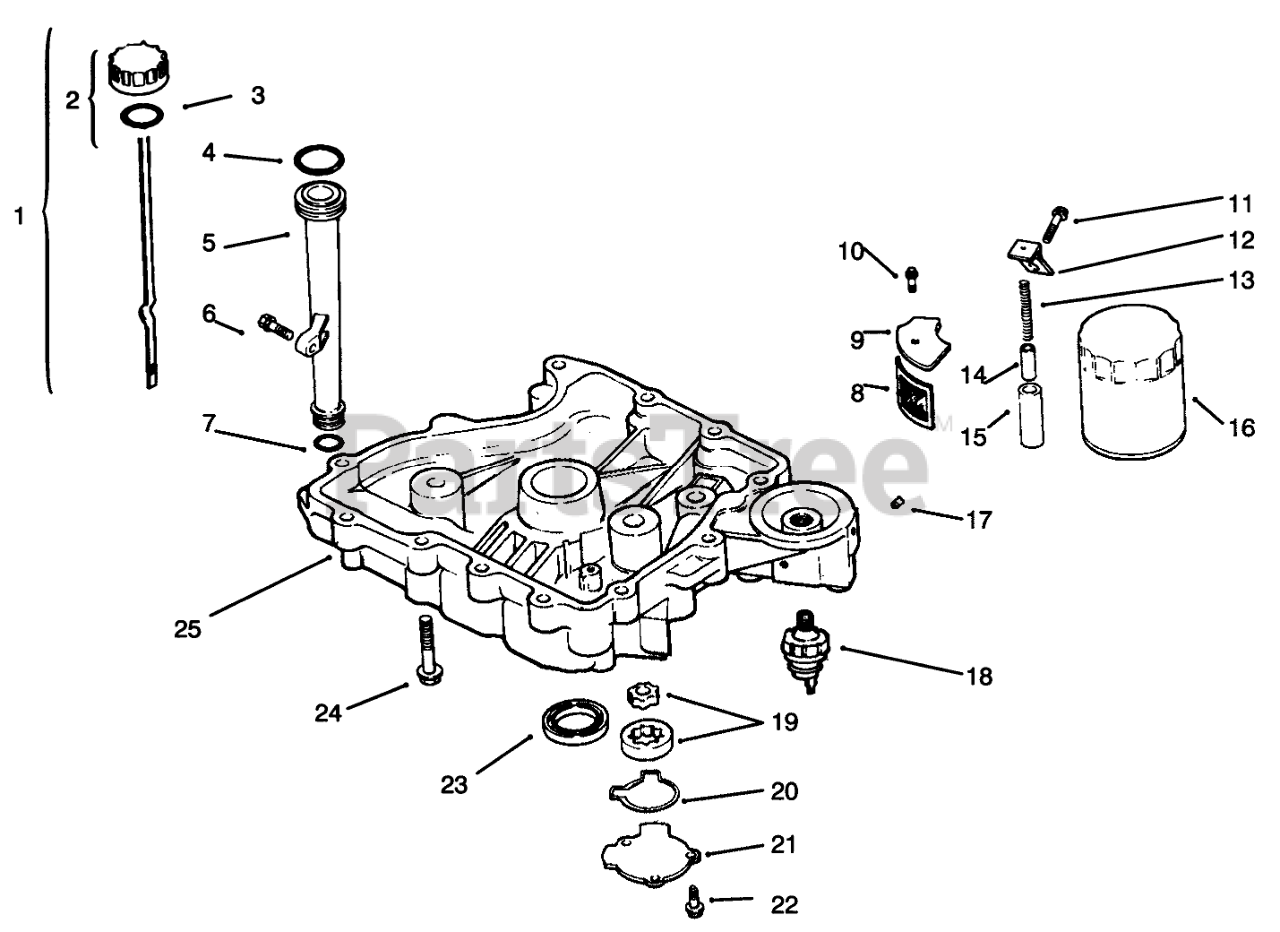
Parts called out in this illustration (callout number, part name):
1	Dipstick INCL 2-3 (Only On: 72042, 72043, 72062, 72063)
2	Kit-Oil Cap INCL 3 (Only On: 72042, 72043, 72062, 72063)
3	O Ring-Fill Cap (Only On: 72042, 72043, 72062, 72063)
4	O Ring-Upper Fill Tube (Only On: 72042, 72043, 72062, 72063)
5	Tube-Oil Fill (Only On: 72042, 72043, 72062, 72063)
6	Screw M5x0.8x20 (Only On: 72042, 72043, 72062, 72063)
7	O Ring-Lower Fill Tube (Only On: 72042, 72043, 72062, 72063)
8	Screen-Oil Pickup (Only On: 72042, 72043, 72062, 72063)
9	Cover-Oil Pickup Screen (Only On: 72042, 72043, 72062, 72063)
10	Screw M5x0.8x16 (Only On: 72042, 72043, 72062, 72063)
11	Screw M10x1.5x25 (Only On: 72042, 72043, 72062, 72063)
12	Bracket-Oil Pump Relief (Only On: 72042, 72043, 72062, 72063)
13	Spring-Oil Relief Valve (Only On: 72042, 72043, 72062, 72063)
14	Piston-Oil Relief Valve (Only On: 72042, 72043, 72062, 72063)
15	Body-Oil Relief Valve (Only On: 72042, 72043, 72062, 72063)
16	Filter-Oil (Only On: 72042, 72043, 72062, 72063)
17	Plug-SH 3/8 NPTF (Only On: 72042, 72043, 72062, 72063)
18	Switch-Oil Pressure (Only On: 72042, 72043, 72062, 72063)
19	Pump-Oil (Only On: 72042, 72043, 72062, 72063)
20	O Ring-Oil Pump Cover (Only On: 72042, 72043, 72062, 72063)
21	Cover-Oil Pump (Only On: 72042, 72043, 72062, 72063)
22	Screw M5x0.8x16 (Only On: 72042, 72043, 72062, 72063)
23	Seal-Crankshaft (Only On: 72042, 72043, 72062, 72063)
24	Screw M8x1.25x45 (Only On: 72042, 72043, 72062, 72063)
25	Pan-Oil (Only On: 72042, 72043, 72062, 72063)
